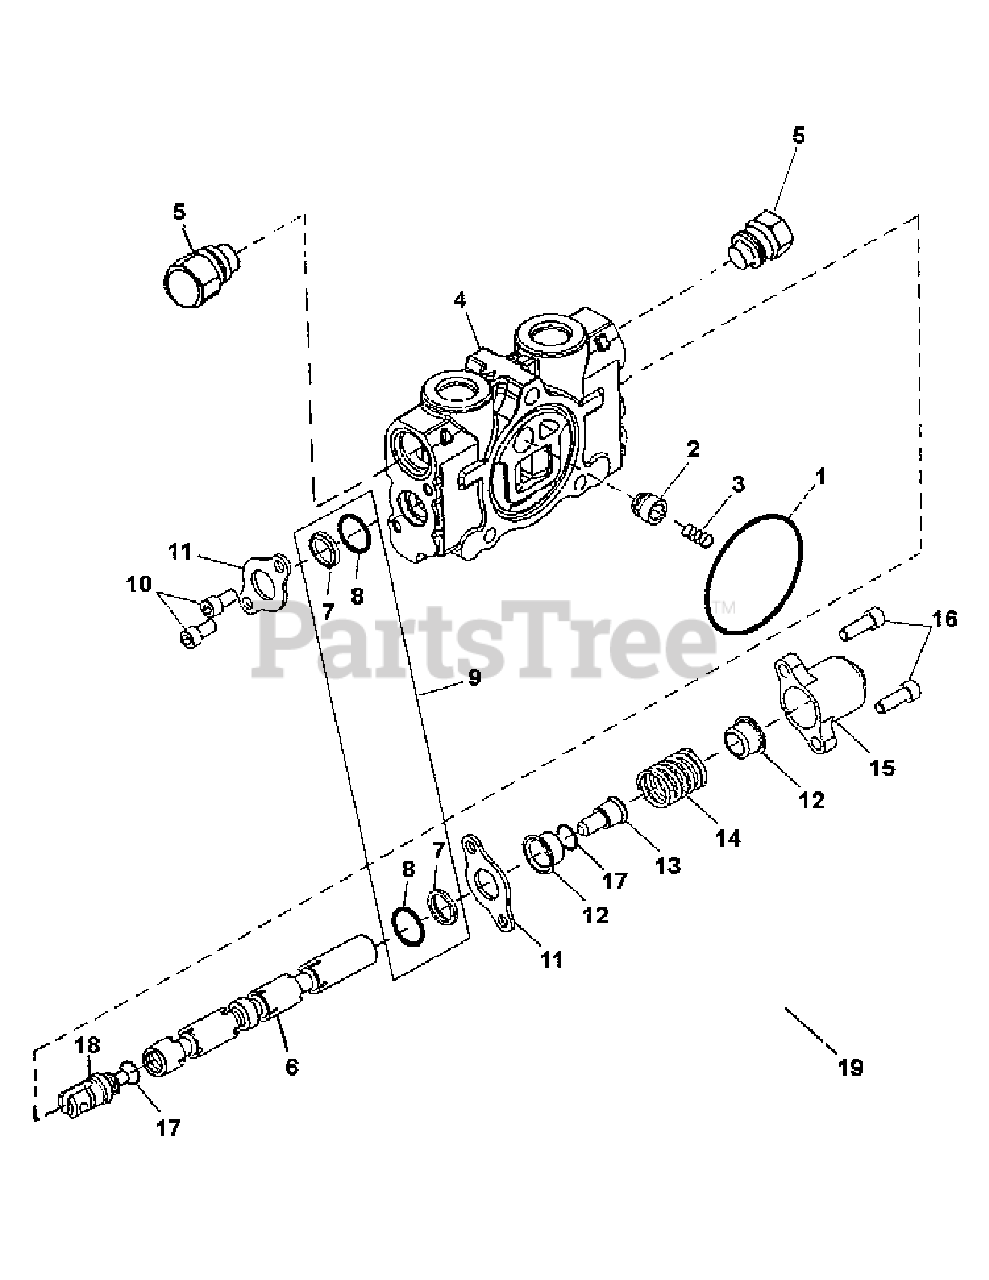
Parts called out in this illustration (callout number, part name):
1	O-RING
2	POPPET, LOAD CHECK
3	SPRING, LOAD CHECK
4	VALVE SECTION
5	PLUG, SHUT OFF
7	WIPER, SPOOL
8	O-RING SPOOL
9	SEAL KIT, MINOR
10	CAP SCREWS, SOCKET HEAD
11	PLATE, RETAINER
12	SEAT, SPRING
13	SCREW, SPRING SEAT
14	SPRING, SPOOL CENTERING
15	CAP, SPRING SPOOL
16	CAP SCREWS, SOCKET HEAD
17	O-RING
18	CLEVIS END
19	VALVE SECTION ASSEMBLY
